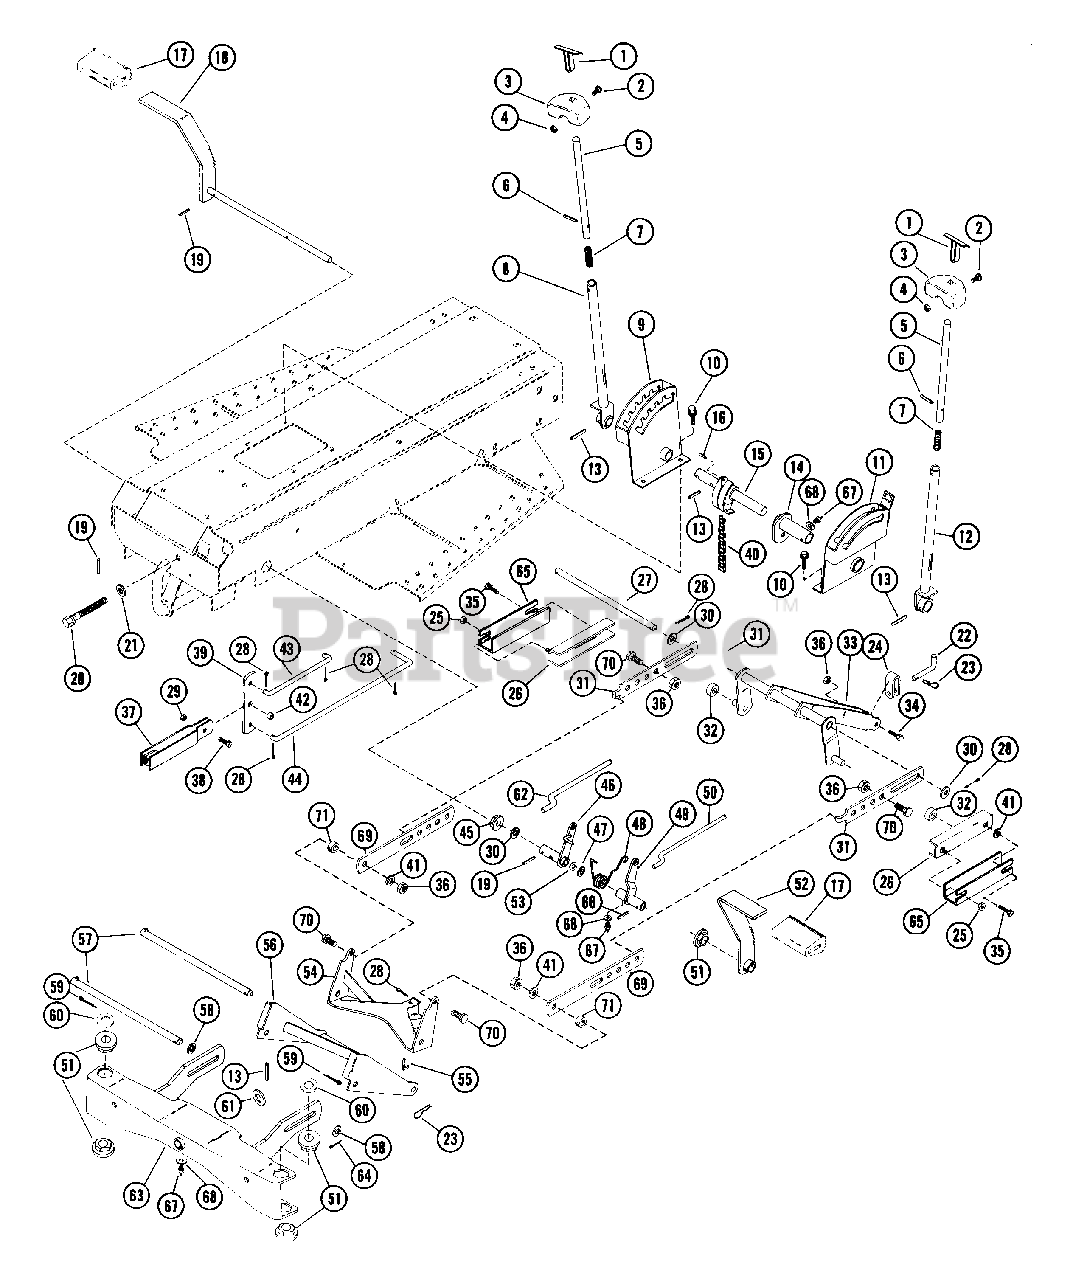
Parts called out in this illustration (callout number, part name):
1	T PLUNGER
2	BLT-HEX 10-24X1.25 FHPL
3	T HANDLE
4	NUT-LK TOP 10-24 PL
6	PIN-ROLL .188X1.50
7	SG-COMP ??X.44X?? WLD 10
8	PAN RAISING HANDLE
9	ATTACHMENT LIFT QUADRANT
10	BLT-SERHFWH .31-18X.50 PL
11	ENGAGEMENT QUADRANT
12	ENGAGEMENT HANDLE
13	PIN-ROLL .250X1.25
14	ENGAGEMENT LEVER
15	MOWER LIFT DRUM
16	PIN-ROLL .156X.88
17	PEDAL COVER
18	BRAKE PEDAL
19	PIN-ROLL .188X1.00
20	CAP SCREW
21	WSHR-FL-STL .505X1.000X.062
22	CLEVIS PIN
23	PIN-HAIR INT .08X.38X1.42 YWZC
24	SWIVEL BLOCK
25	NUT-FLG. .312-18 PL
26	PAN RAIL
27	FLOAT PIN
28	PIN-COTR .12X1.0 PL
29	NUT-LK .312-18 GR A PL
30	WSHR-FL-STL .531X1.062X.095 PL
31	REAR HANGER STRAP
33	REAR MOWER HANGER
34	BLT-HEX .38-16X1.75 PL GR2
35	BLT-SERHFWH .31-18X.75 PL
36	NUT-LK-CTR .375-16 GR A PL
37	ADJUSTMENT YOKE
38	BLT-HEX .31-18X.88 PL GR2
39	PIVOT LINK
40	ROLLER CHAIN
41	WSHR-FL-STL .38X.875X.083 PL
42	SPACER BUSHING .5 X .32 X .21
44	MOWER ENGAGEMENT LINK
45	FLANGE BUSHING
46	BRAKE ARM
47	WAVE WASHER .531X.781X.125FH
48	SG-TORS .088X.75X3.0
49	CLUTCH ARM
50	CLUTCH ROD
51	FLANGE BUSHING
52	CLUTCH PEDAL
53	WSHR-FL-STL .505X.875X.024 PL
56	MOWER LIFT ARM
57	HANGER PIN
58	WSHR-FL-STL .505X.880X.072 PL
59	PIN-COTR .12 X 1.25 PL
60	WSHR-FL-STL .755X1.375X.062 PL
61	WSHR-FL-STL .755X1.375X.125
62	BRAKE ROD
63	AXLE
64	PIN-COTR .09X1.0 PL
65	CHANNEL
66	PIN-ROLL .188X1.25
67	SPIN DRIVE ZERK FITTING
68	WSHR-FL-STL .265X.500X.087 PL
69	HANGER ADJUSTMENT LINK
70	BLT-HEX .38-16X.75 PL GR5
71	BSHG-SLV .377X.624X.235
